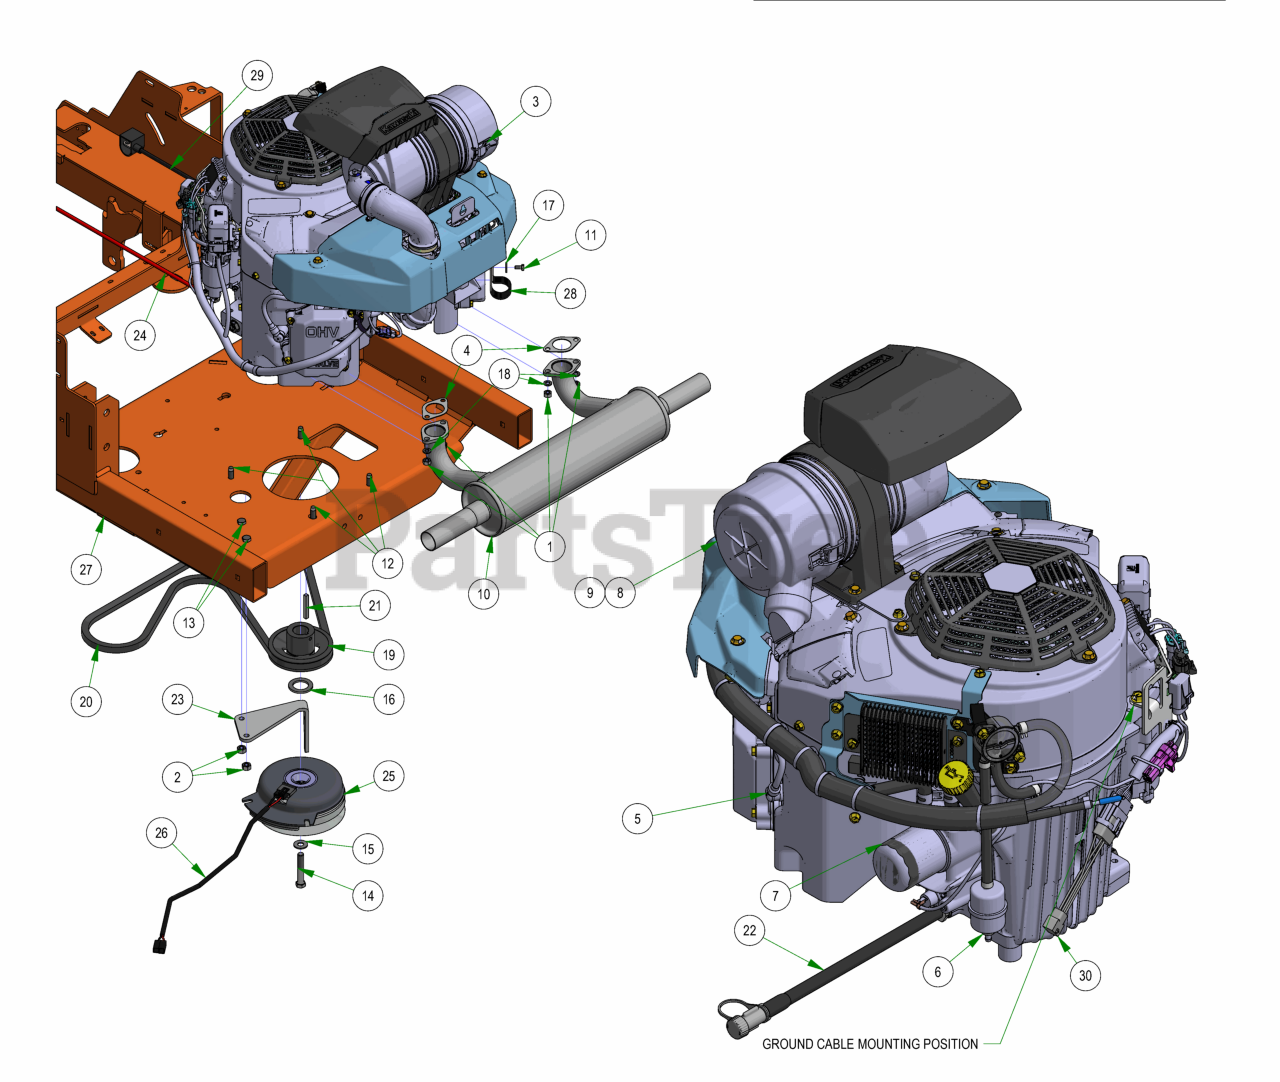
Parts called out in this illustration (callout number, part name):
1	M8-1.25 DIN 934 HEX NUT (CL.8) ZINC
2	3/8-16 HEX NUT ZINC
3	Kawasaki FX1000EFI 38.5HP
4	Exhaust Gasket
5	Spark Plug - Kawasaki
6	Universal Inline Fuel Filter
7	Oil Filter
8	Canister Air Filter- Outer
9	Canister Air Filter- Inner
10	2019 Rebel/Rogue Kawasaki 1000 Muffler
11	M6-1.0 X 12MM DIN 933 HEX TAP BOLT (CL 8.8) ZINC
12	3/8-16 X 1-1/8HEX WASHER UNSLOT SERRATED (TRI-LOB) TRS
13	3/8-16 X 1-1/4 HEX CAP SCREW (GR.5) ZINC
14	7/16-20 X 2-1/2 HEX Bolt GR 8 W/ Patch
15	3/8 FLAT WASHER USS (1" OD) ZINC
16	1.140 ID X 1.750 OD X .132 THICK FLAT WASHER PLAIN
17	1/4 USS FLAT WASHER (3/4 OD) ZINC
18	5/16 SPLIT LOCKWASHER ZINC
19	4 3/4 Motor Pulley
20	2019 Rogue Pump Belt 68"
21	1/4 X 2 SQ MACHINERY KEY 1018 STL PLAIN
22	Kawasaki Oil Drain
23	PTO Engager Holder
24	24" Red Battery Cable
25	Clutch Assembly
26	Clutch Pigtail
27	2023 Rogue Frame - Painted
28	Diesel Hydraulic Hose Clamp
29	Starter Cable
30	Harness Adaptor for Kawasaki EFI
